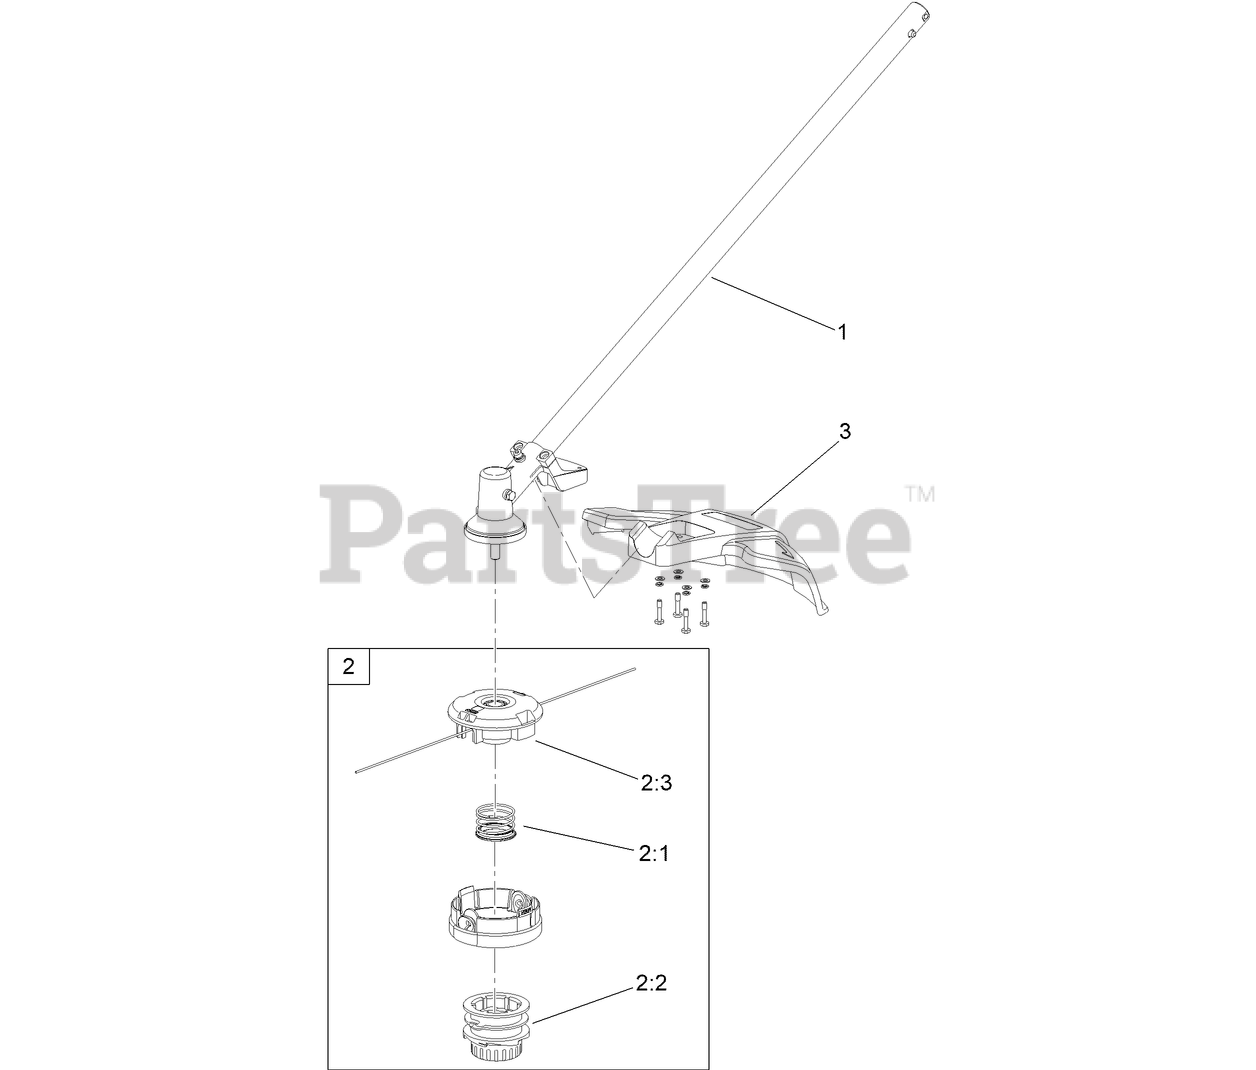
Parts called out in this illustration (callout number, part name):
1	Shaft
2:1	SPRING-SPOOL
2:2	CAP-FEED, BUMP
